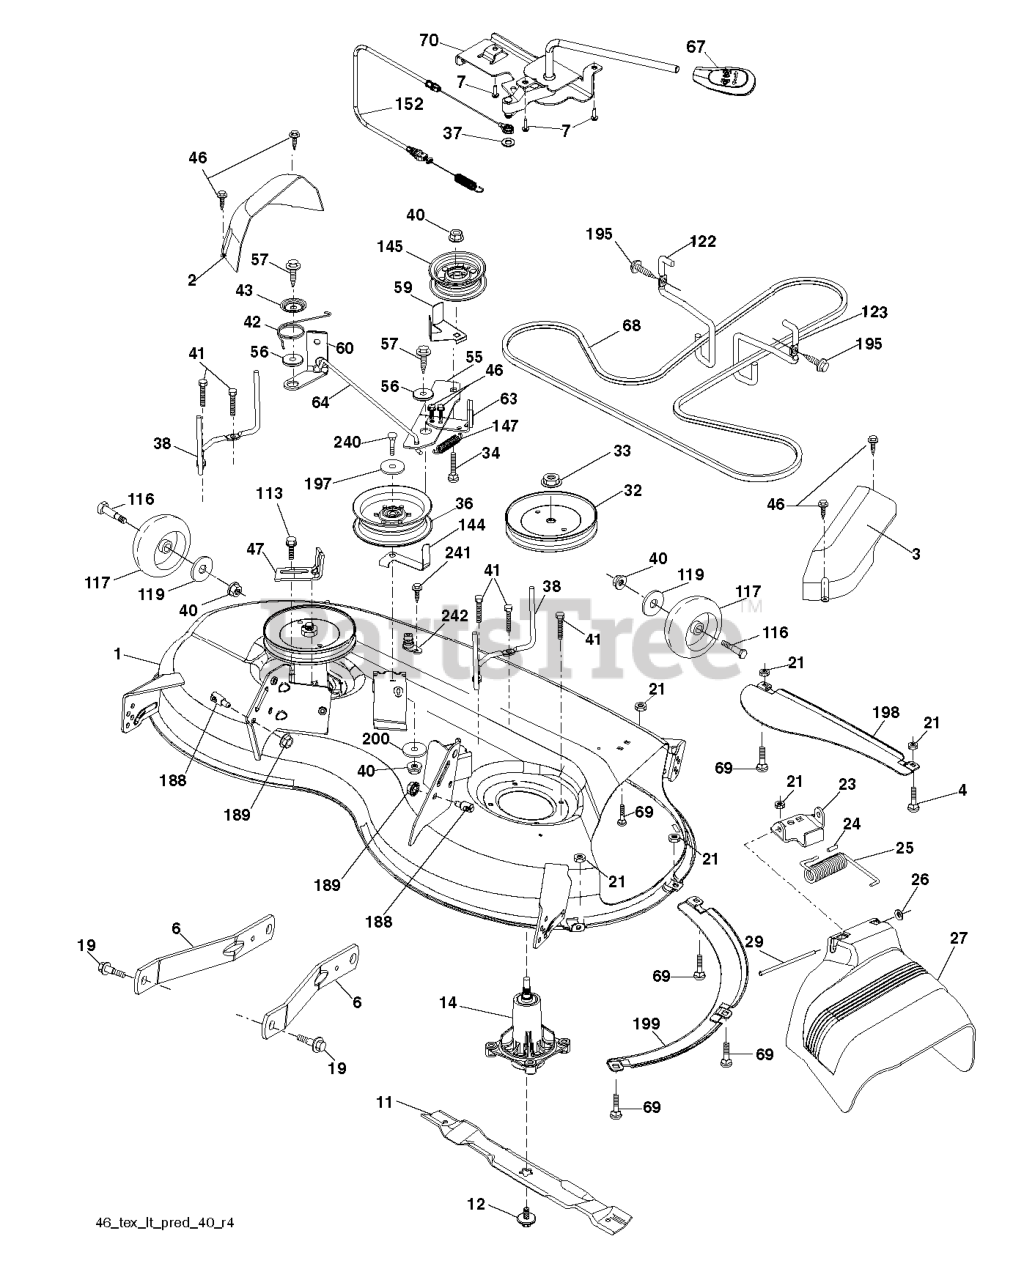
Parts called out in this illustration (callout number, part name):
1	RP DECK.WELDMENT.46"(2GA.WHL)
2	COVER.MANDREL.RH.46"
3	COVER.MANDREL.LH.46"
4	SCREW HEXAGON HEAD SCREW 5/16-
6	ARM.SUSPENSION.MOWER.R
11	BLADE.MOWER.46".HI.LIFT
12	SCREW.SEMS.7/16-20X1.HEX.HEAD
14	KIT.MANDREL.NONGREASE.TALL
19	BOLT.SHOULDER
23	BRKT.DEFLECTOR.38"2005+
24	CAP-SLEEVE LT
25	SPRING.TORSION.DEFLECT
26	NUT PUSH M
27	SHIELD.DEFLECTOR.MOWER.46"BLAC
32	PULLEY.MANDREL.5.438.PD
34	GSPW Bolts
36	PULLEY.IDLER.2006
37	WASHER PLAIN WASHER 3/8 X 0.08
38	KEEPER.BLT.PNT.MNDRL.PULL.6.25
40	NUT LOCK FLG 3/8-16 UNC
41	BOLT.HEX.WASHR.HED.313-18X1.19
42	SPRING.TORSION.BRAKE
43	SRPING.TORSION.RETAINE
46	SCREW.1/4-20X5/8
47	BRKT.CLUTCH.CABLE
56	SPACER.RETAINER
57	SCREW 3/8-16X1
59	GUARD, BELT
60	ARM BRAKE MOWER RH 38"
63	ARM BRAKE MOWER
64	LINKAGE BRAKE
67	HANDLE.CLUTCH.CABLE.LT
68	V-BELT
70	CLUTCH.ASM.MANUAL.YT.PREDATORQ
113	BOLT.5/16HEX.WHS.HD
117	WHEEL.GAUGE.RALLY.NARROW
122	KEEPER BELT ENGINE LH
123	KEEPER BELT RH
144	KEEPER.BELT.MOWER
145	PULLEY.IDLER.48"PRIMARY
147	SPRING RETURN
152	CABLE.MECHANICAL.CLUTCH
188	STUD.W/"D"ANTI-ROTATION
195	SCREW, 3/8-16X3/4
198	BAFFLE CENTER FRONT
199	BAFFLE FRONT RH
200	WASHER.13/32 X 1 X 1/2.11GUARD
240	BOLT-HEX EAK
241	SCREW.TT.#10-32X.5.3/8.FLANGE
242	PORT.WASHOUT
